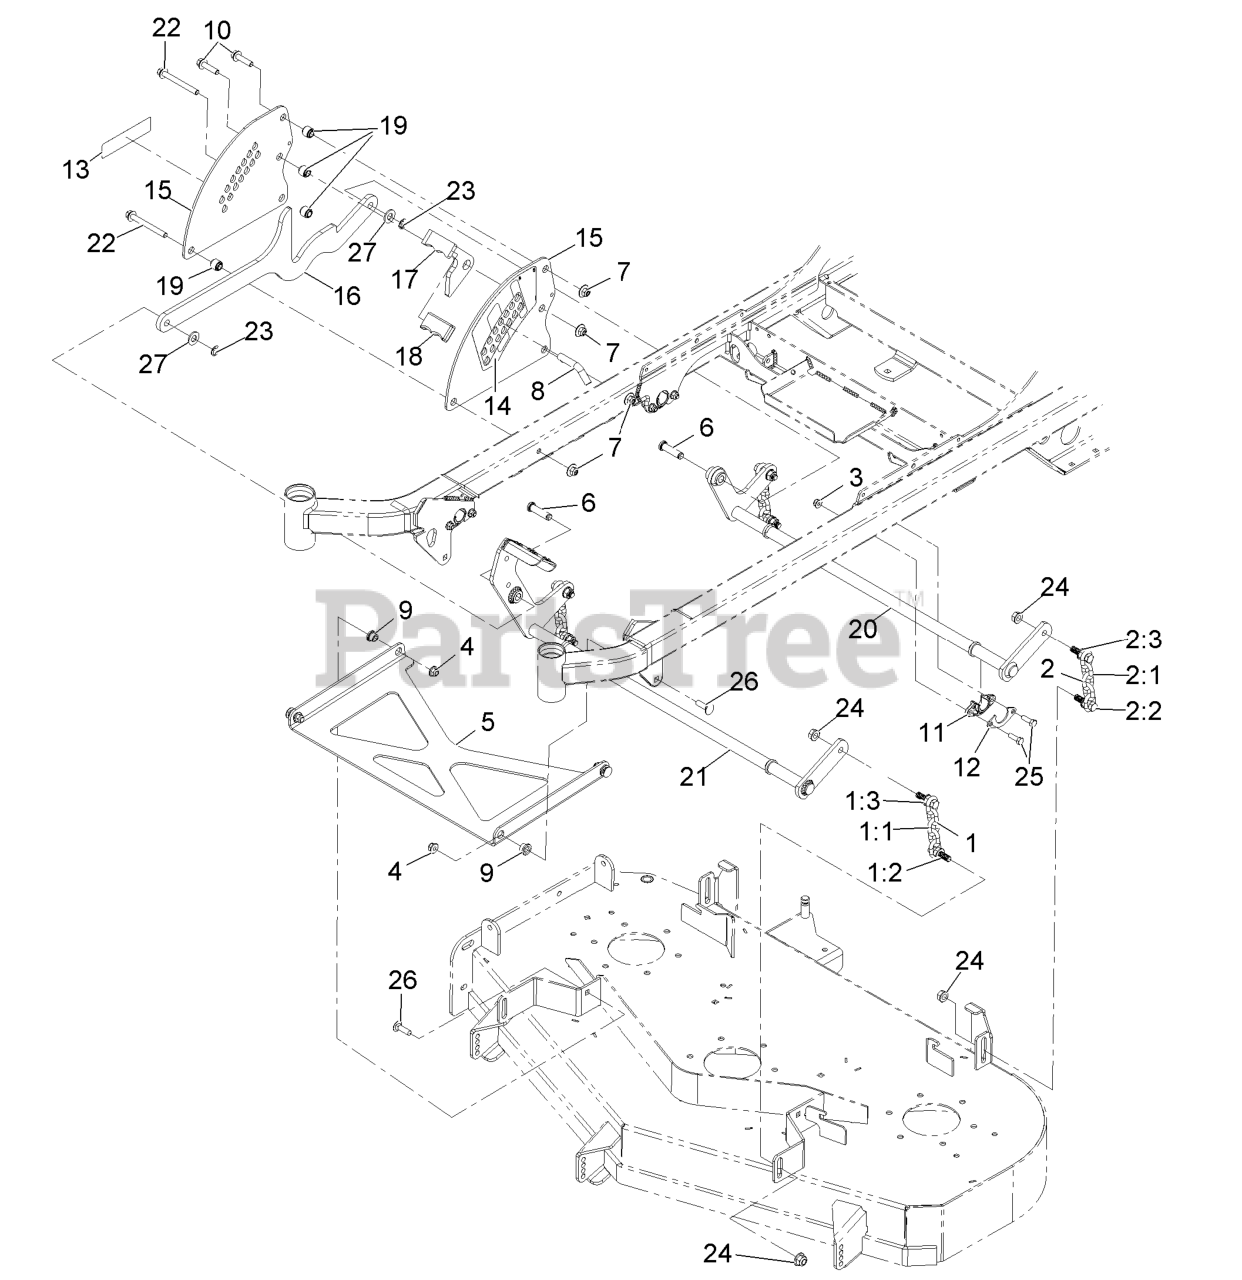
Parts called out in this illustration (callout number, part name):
1	DECK CHAIN ASM
1:1	CHAIN-LIFT, DECK
1:2	SCREW-HH
2	DECK CHAIN ASM
2:1	CHAIN-LIFT, DECK
2:2	SCREW-HH
3	NUT-HF, NI
4	NUT-HF, NI
5	STRUT-DECK
6	PIN-CLEVIS
7	Nut-Nyloc 3/8-16 Flg
8	PIN-HOC
9	BUSHING-FLANGED
10	SCREW-HHF
11	BUSHING-FLANGE
12	GUSSET-LIFT, DECK
13	DECAL-S-SERIES
14	DECAL-HEIGHT OF CUT
15	PLATE,DECK LIFT
17	TRANSPORT LOCK-HOC
18	GRIP-FLAT
19	SPACER-STEP, DOUBLE
20	WLD,DECK LIFT SHAFT-REAR
21	WLD,DECK LIFT SHAFT-FRT
22	SCREW-HHF
23	RING-RETAINING, EXTERNAL
25	SCREW-HH
26	BOLT-CARR
27	WASHER-FLAT
